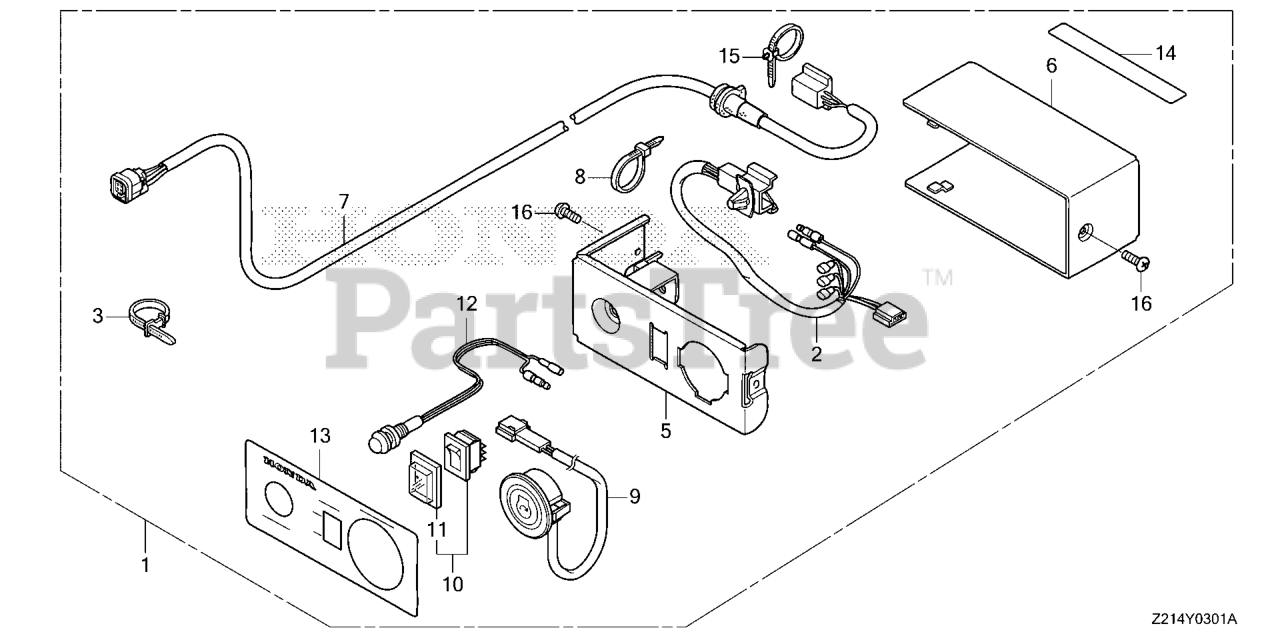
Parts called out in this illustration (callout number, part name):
1	CONTROL KIT, REMOTE (10M) *NH105* (MAT BLACK)
1	CONTROL KIT, REMOTE (20M) *NH105* (MAT BLACK)
1	CONTROL KIT, REMOTE (30M) *NH105* (MAT BLACK)
2	HARNESS ASSY., REMOTE CONTROL (AG)
3	BAND, WIRE Use up to Frame SN 1001879.
5	PANEL, REMOTE CONTROL *NH105* (MAT BLACK)
6	COVER, REMOTE CONTROL *NH105* (MAT BLACK)
7	CABLE ASSY., REMOTE CONTROL (10M)
7	CABLE ASSY., REMOTE CONTROL (20M)
7	CABLE ASSY., REMOTE CONTROL (30M)
8	TIE, CABLE (C)
9	SWITCH ASSY., START
10	SWITCH ASSY., MAIN
11	CAP,SELECT SW
12	LED ASSY.
13	MARK, REMOTE CONTROL (NOT AVAILABLE)
14	MARK, SHUTOFF NOTE
15	BAND, HARNESS (98MM) (NATURAL)
16	SCREW, PAN (4X8)
